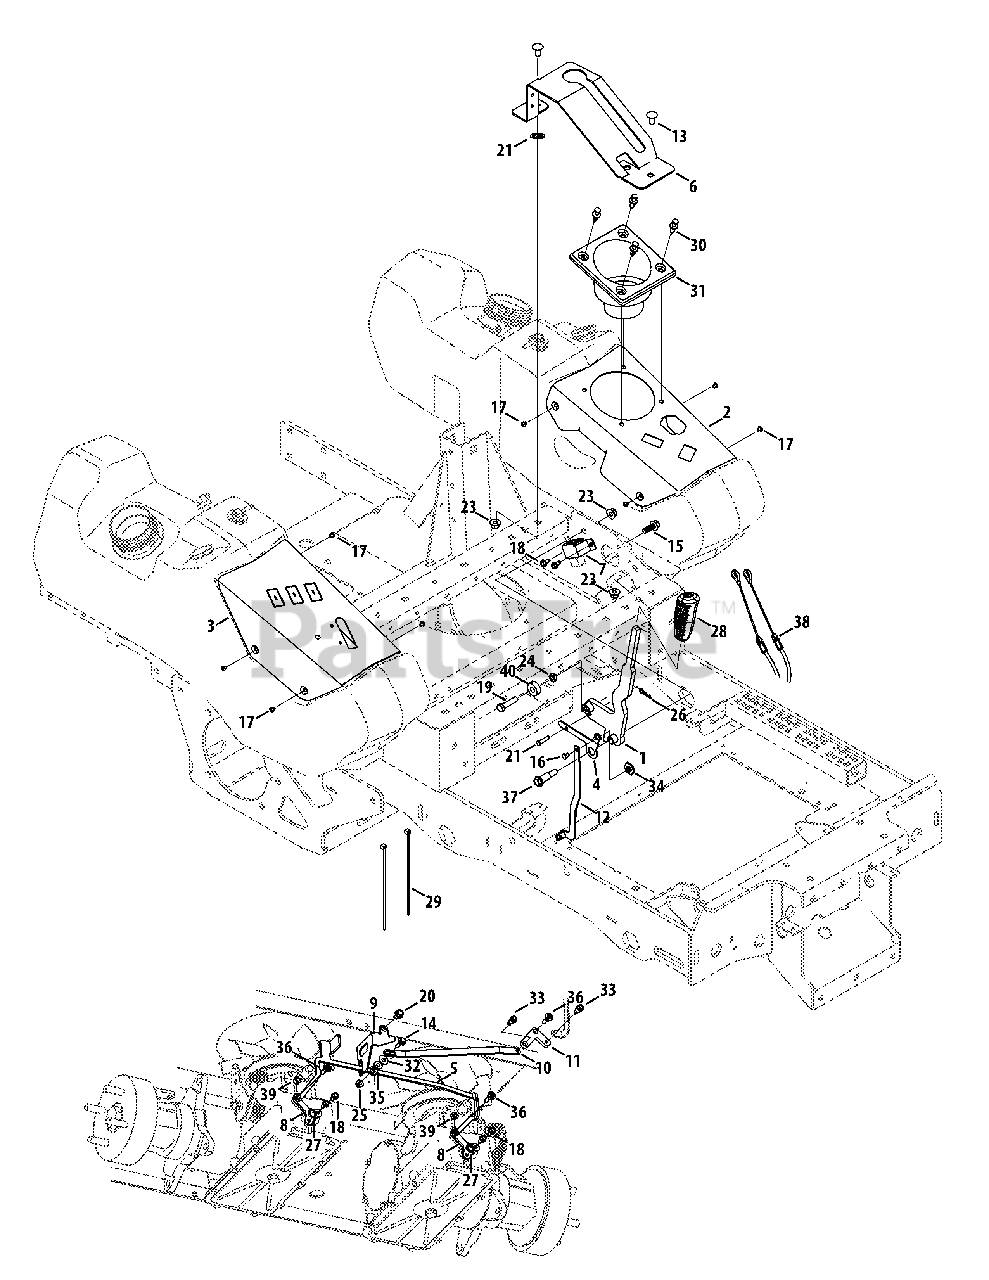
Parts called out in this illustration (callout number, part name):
1	Brake Handle Assembly
2	LH Control Panel
3	RH Control Panel
4	Dump Valve Release Lever
5	Dump Valve Actuator Bracket
6	Boot Brake Bracket
7	Brake Switch Mount
8	Transmission Bypass Lever
9	Neutral Switch Bracket
10	Transmission Actuator Arm
11	Neutral Pivot Control Lever
12	Neutral Arm
13	Carriage Bolt, 3/8-16 x .75
14	Hex Flange Screw, 1/4-20 x .75
15	Screw, 3/8-16 x 1.00
16	Screw, M6 x 8mm
17	Machine Screw, #10-32 x .25
18	Hex Flange Screw, 1/4-20 x .500
19	Hex Cap Screw, 3/8-16 x 1.50
20	Screw, 5/16-18 x .50
21	Clevis Pin, .25 x 1.00
22	Push Nut, 3/8
23	Nut, 3/8-16, Flangelock
24	Jam Nut, 3/8-16
25	Nut, 1/4-20, Hexflange
27	Retainer Ring
28	Grip, .50 ID
29	Cable Tie
30	Rivet, .3125
31	Cup Holder
32	Flat Washer, .283 x .750 x .030
33	Shoulder Screw, .342 x .335, 1/4-28
34	Shoulder Spacer, M6
35	Shoulder Spacer, .375 x .625 x .20
36	Shoulder Screw, .375 x .280, 1/4-14
37	Shoulder Bolt, .50 x .925, 3/8-16
38	Brake Cable
39	Spacer, .256 x .500 x .240
40	Spacer, .406 x 1.00 x .38
